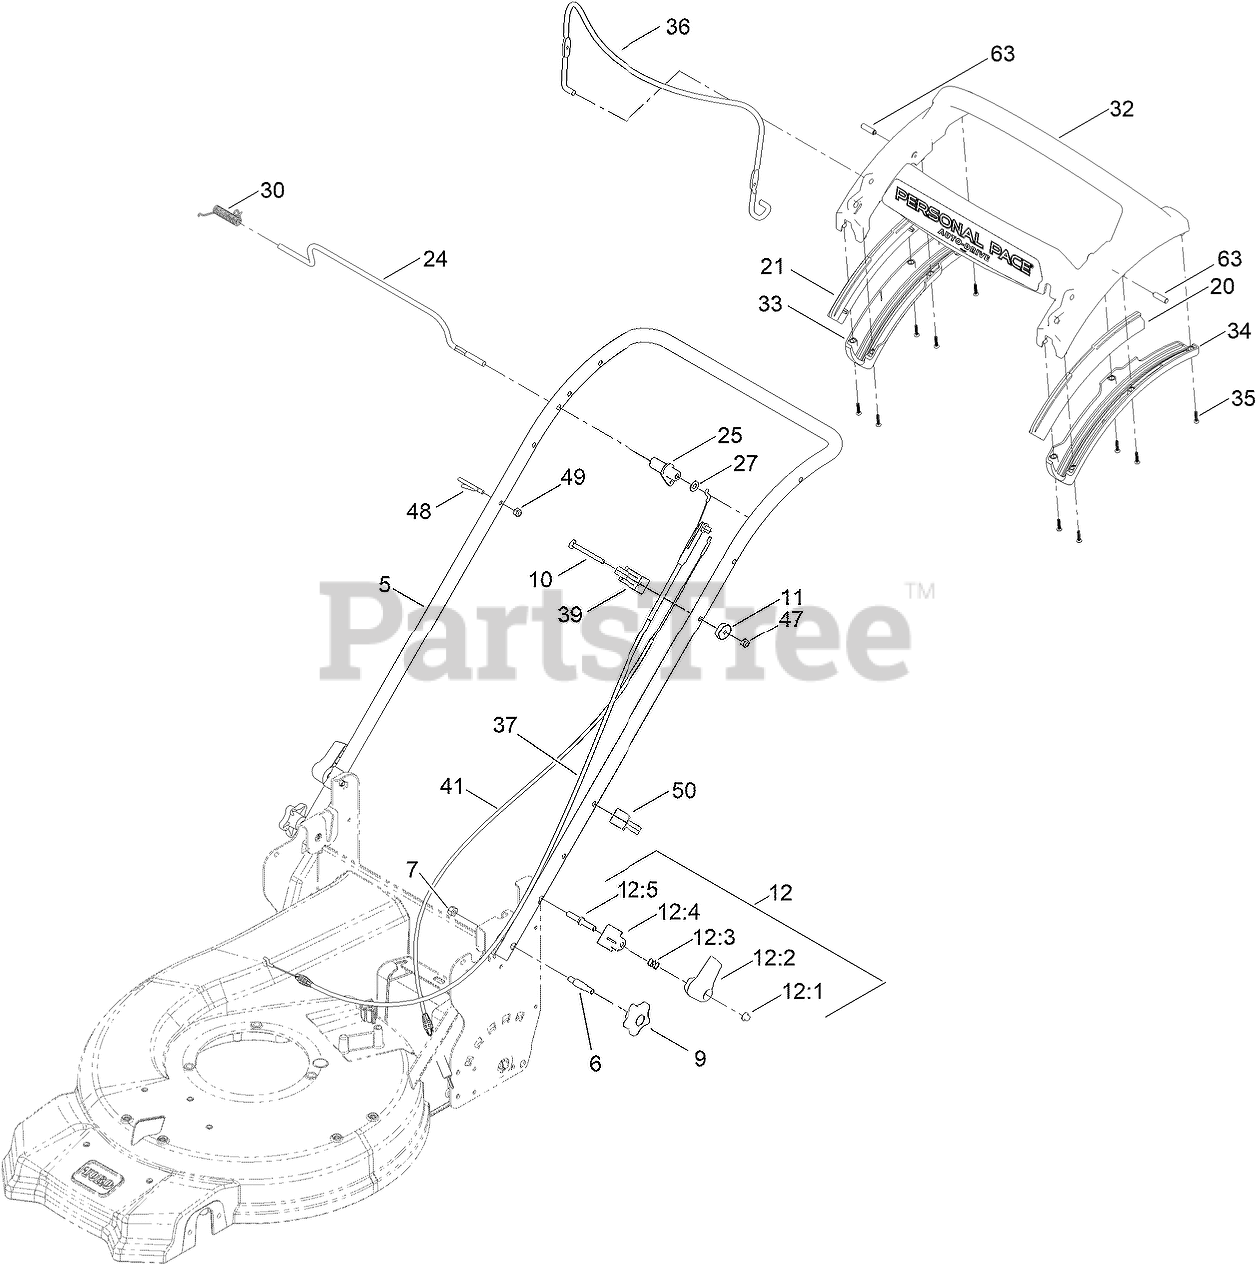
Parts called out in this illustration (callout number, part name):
5	HANDLE-CURVED
6	BOLT-SHOULDER, HANDLE
7	NUT-HEX
9	KNOB-HANDLE
10	SCREW-CARR
11	WASHER-CURVED
12	QUICK RELEASE ASM
12:1	NUT-PUSH
12:2	LEVER-RELEASE
12:3	ANCHOR-SPRING
12:4	SPRING-COMPRESSION
12:5	ROD-RELEASE
20	GUIDE-CURVED, LH (RWD)
21	GUIDE-CURVED, RH (RWD)
24	ROD-CONTROL, TRACTION
25	LEVER-TRACTION, RWD
27	WASHER-PLAIN
30	SPRING-TORSION
32	HANDLE-PERSONAL PACE, CURVED
33	BOTTOM-HANDLE, RH
34	BOTTOM-HANDLE, LH
35	SCREW-PPH
36	BAIL-BRAKE
37	CABLE-BRAKE, PP BS
39	ANCHOR-CABLE, RWD
41	CABLE-TRACTION, RWD (PP)
47	NUT-LOCK, NI
48	GUIDE-ROPE
49	NUT-HEX
50	GUIDE-CABLE
63	PIN-HANDLE, PP
